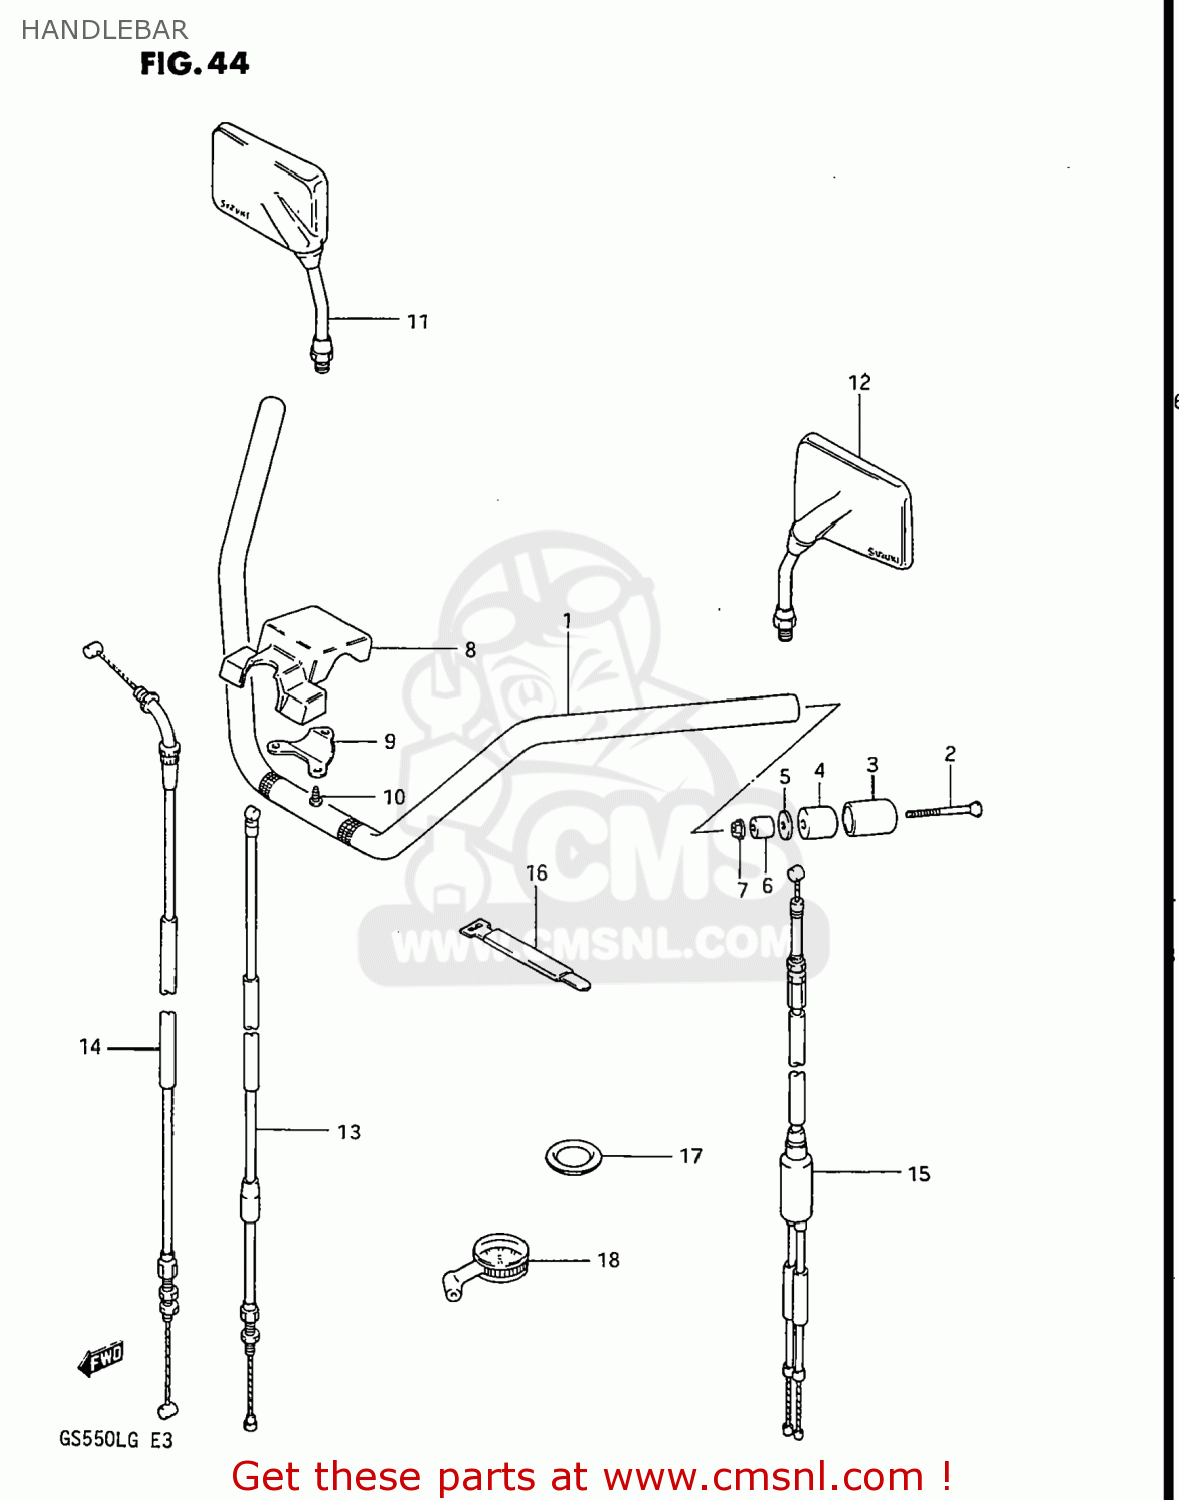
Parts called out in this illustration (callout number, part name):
1	HANDLEBAR
2	SCREW
3	CAP,BALANCER
4	BALANCER,HANDLE
5	SPACER,BALANCER
6	EXPANDER,HANDLE BALANCER
7	NUT
8	COVER,STEERING HEAD
9	BRACKET,STEERING HEAD
10	SCREW
11	MIRROR ASSEMBLY,REAR VIEW
12	MIRROR ASSEMBLY,LEFT
13	CABLE ASSY,CLUTCH
14	CABLE ASSEMBLY,THROTTLE
15	CABLE COMP,STARTER
16	CLAMP(L:250)
17	GROMMET
18	GAUGE ASSY,AIR PRESSURE
